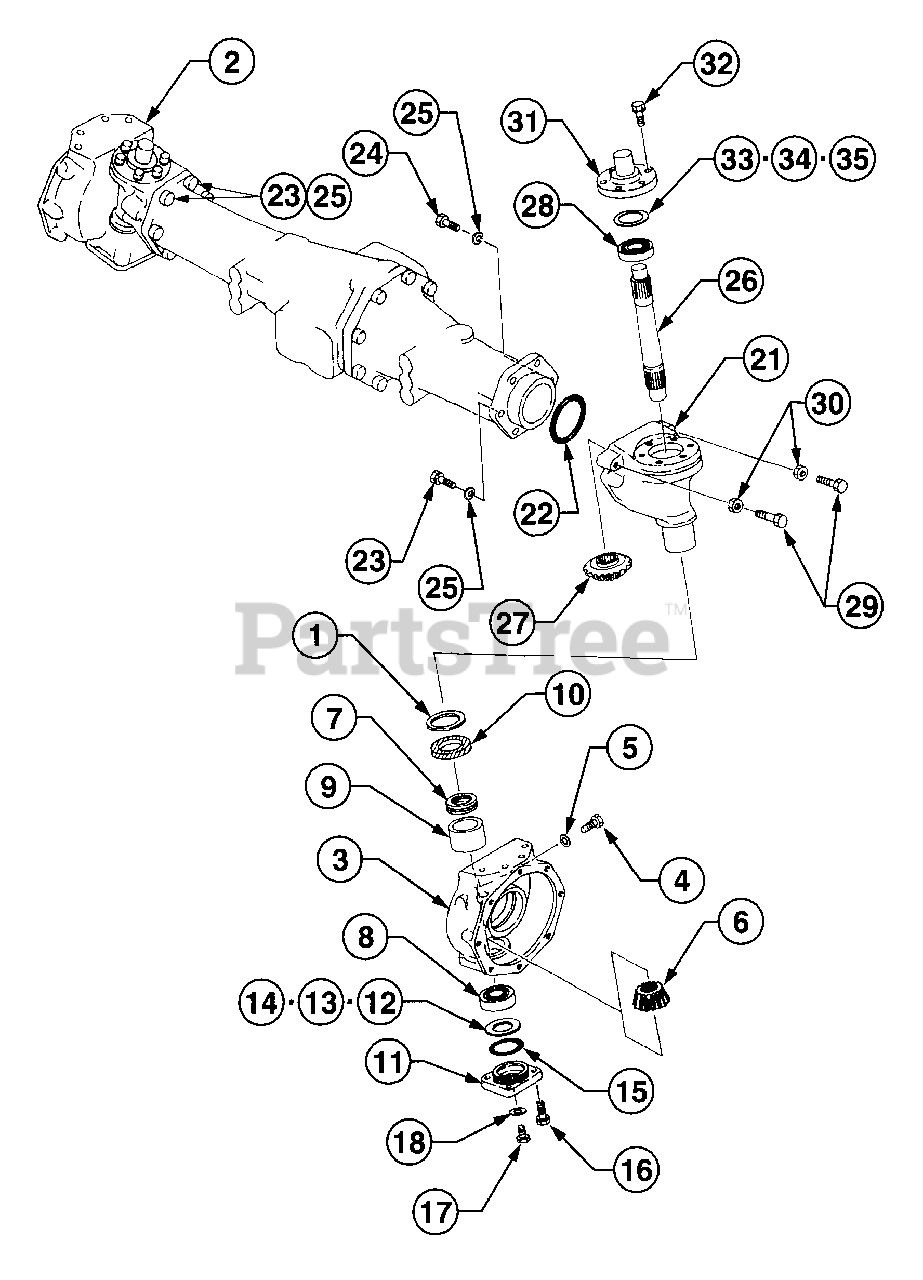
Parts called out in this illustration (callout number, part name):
1	SI. Sleeve
2	Case R.H., Gear
3	Case L.H., Gear
7	Bearing, Thrust
8	Bearing, Ball
10	Seal, Oil
12	Liner, t=0.15
16	Bolt, w/washer
21	Case, Kingpin
23	Bolt, w/Washer
24	Bolt
25	Washer, Spring
28	Bearing, Ball
33	Liner, t=0.15
